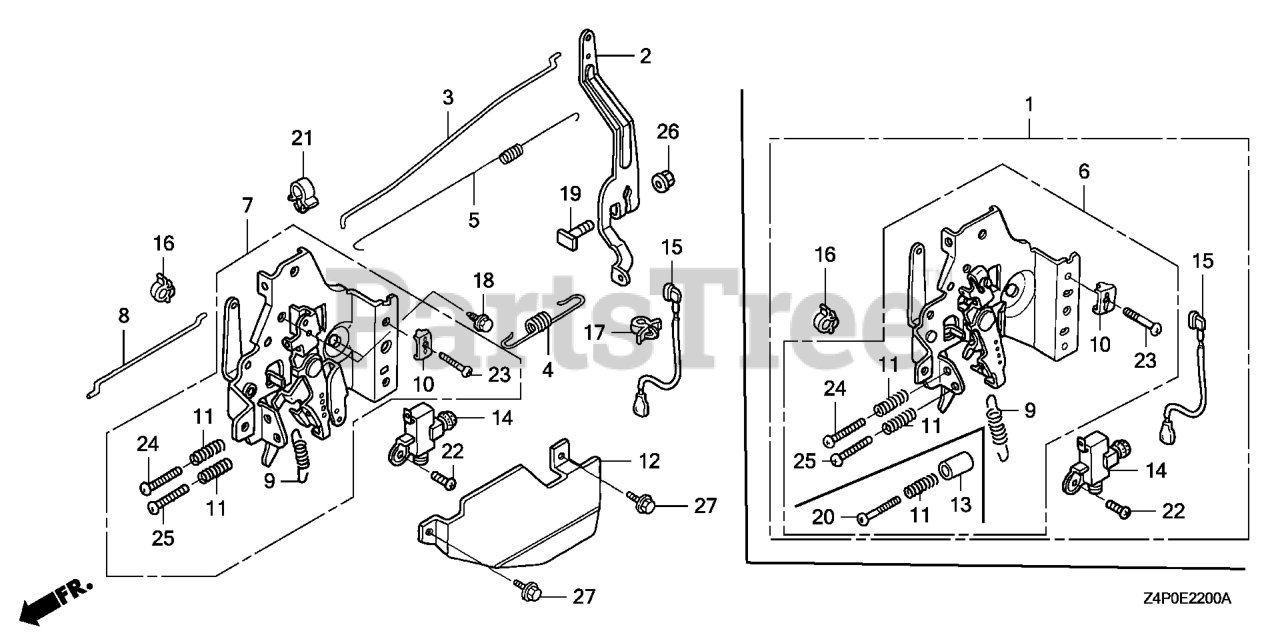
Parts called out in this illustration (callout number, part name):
1	CONTROL ASSY.
2	ARM, GOVERNOR
3	ROD, GOVERNOR
4	SPRING, GOVERNOR (STD)
5	SPRING, THROTTLE RETURN
8	ROD, CHOKE
9	SPRING, LEVER
10	HOLDER, CABLE
11	SPRING, CONTROL ADJUSTING Use from Engine SN 2327377.
12	PROTECTOR, CONTROL
13	COLLAR, STOPPER
14	SWITCH ASSY., ENGINE STOP
15	WIRE, STOP SWITCH
16	HOLDER, STOP SWITCH WIRE
17	CLAMP, HARNESS
18	BOLT, FLANGE (6X12) (CT200)
19	BOLT, GOVERNOR ARM
20	SCREW, RECESSED (5X28)
21	CLIP, HARNESS
22	SCREW, PAN (4X8)
23	SCREW, PAN (5X16)
24	SCREW, PAN (5X20)
26	NUT, FLANGE (6MM)
27	BOLT, FLANGE (6X10)
